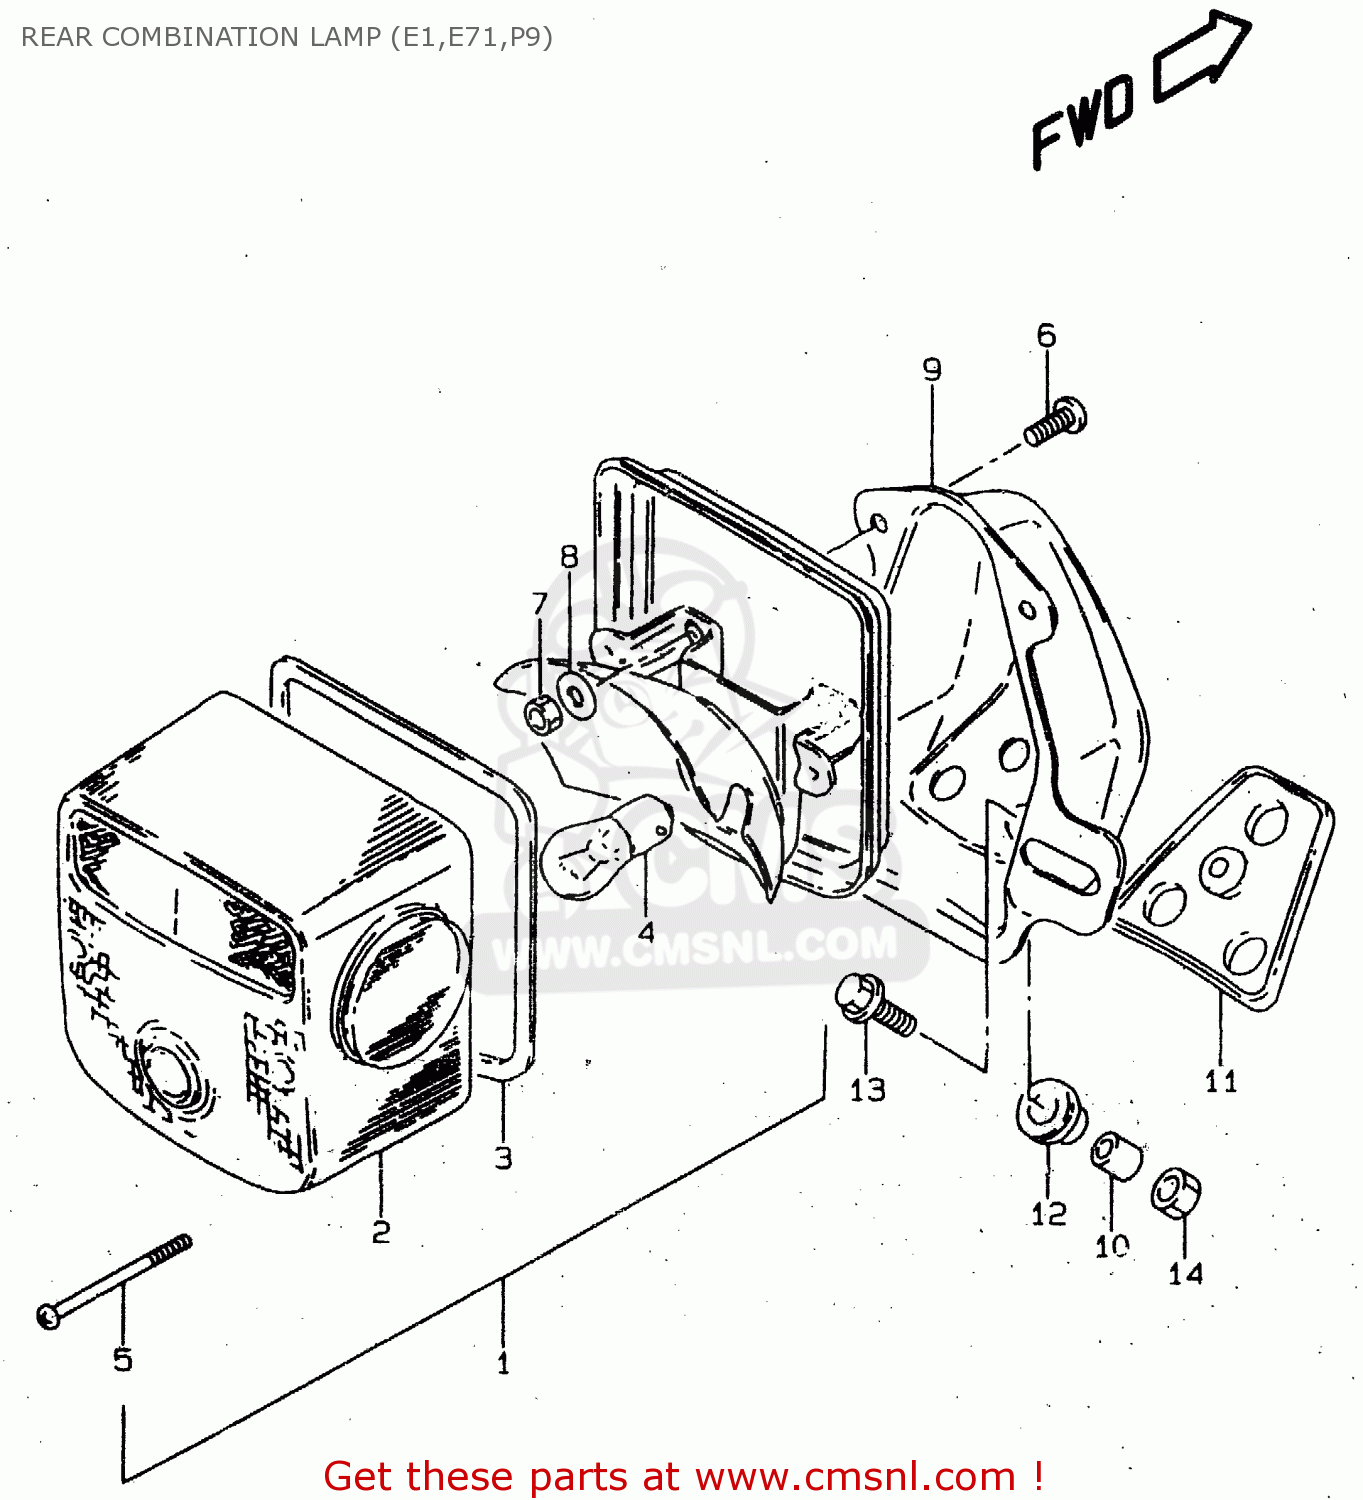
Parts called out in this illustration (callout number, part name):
1	LAMP UNIT, TAIL
2	LENS,RR COMBIN
3	GASKET (NAS)
4	BULB(12V23W)
5	SCREW (4X55)
6	SCREW
7	NUT
8	WASHER
9	BRACKET UNIT,TAIL LAMP
10	SPACER
11	CUSHION
12	CUSHION
13	BOLT(6X20)
14	NUT 6MM
